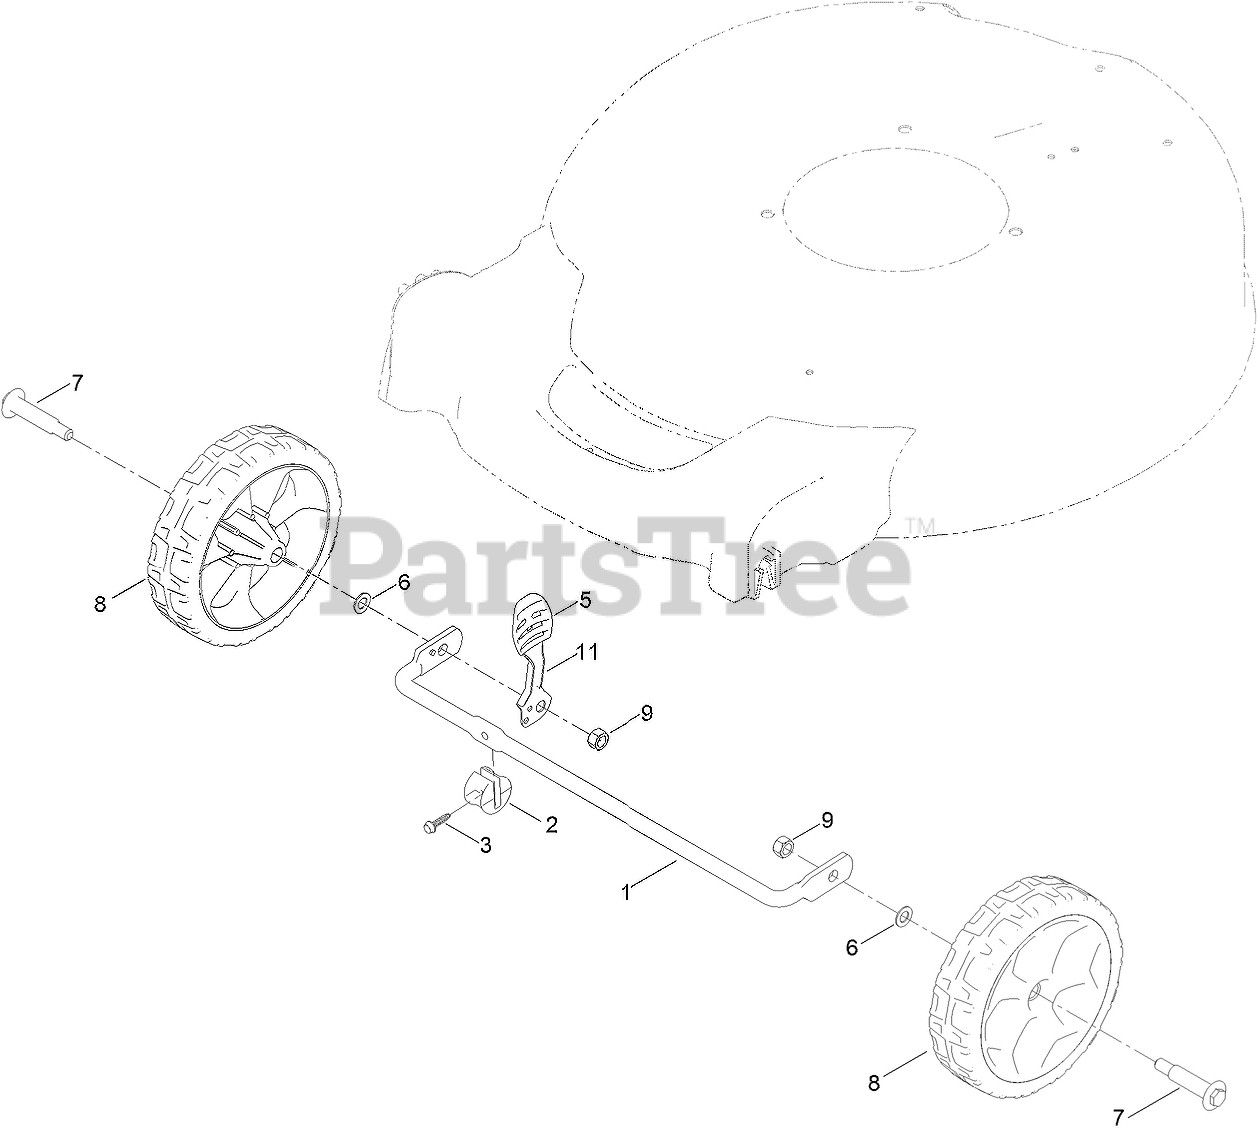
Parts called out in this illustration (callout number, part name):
1	AXLE-FRONT
2	STOP-AXLE
3	SCREW-PLASTIC, HWH
5	KNOB-LEVER, HOC
6	WASHER
7	BOLT-SHOULDER
8	7 INCH WHEEL ASM
9	LOCKNUT
11	ARM-SPRING
